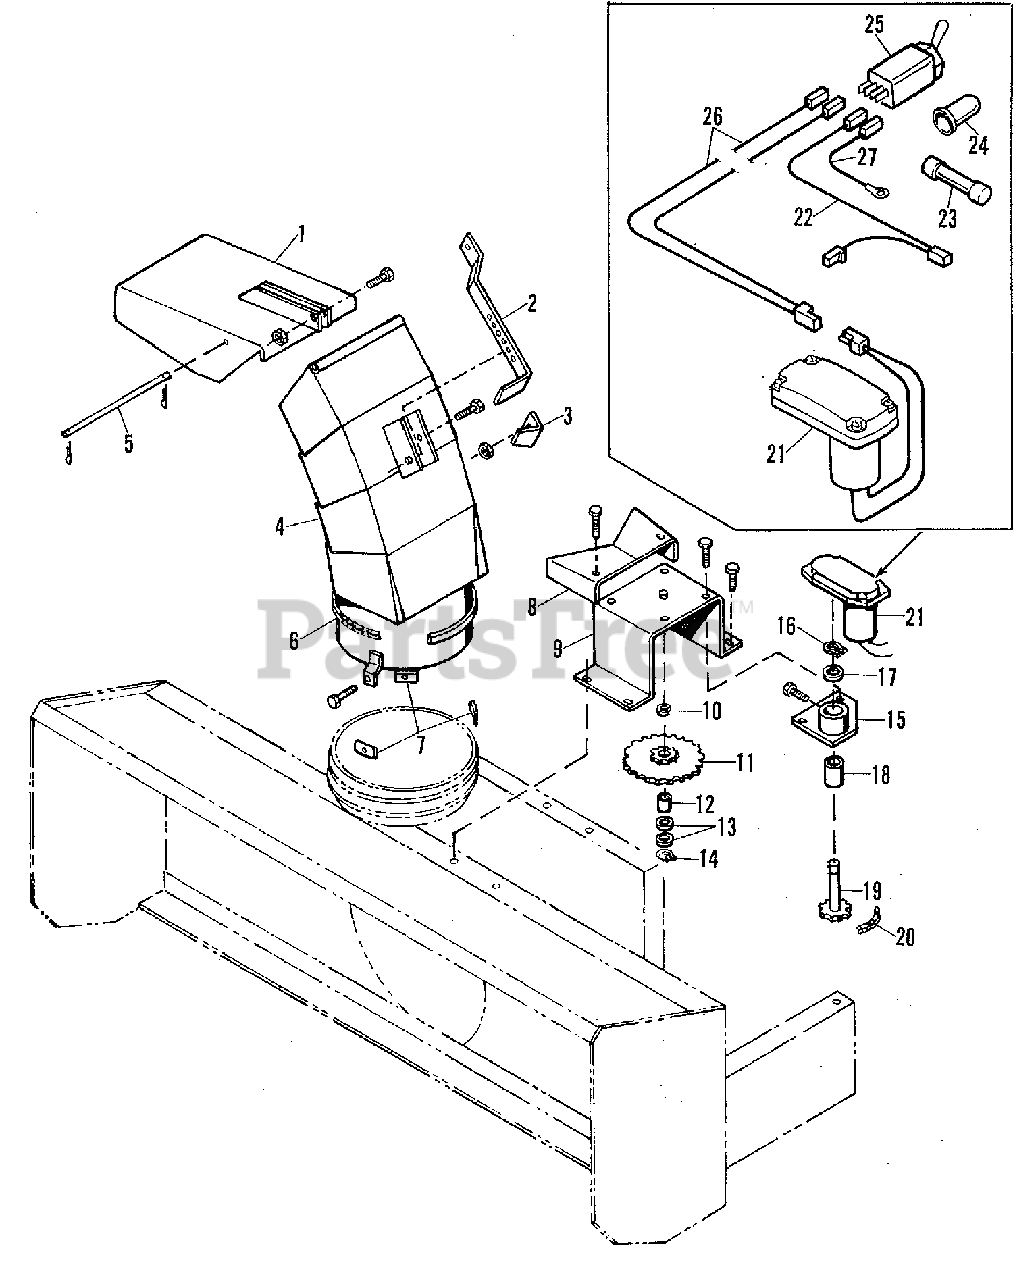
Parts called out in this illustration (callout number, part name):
1	CAPSCREW, 1/2NC x 1-1/4
1	NUT, Huglock, 1/2NC
3	LOCK, Adjuster
3	CAPSCREW, 1/2NC x 1
3	NUT, Huglock, 1/2NC
4	SPOUT ASSEMBLY
4	CAPSCREW, 3/8NC x 3/4
4	WASHER, Plain, 7/16 x 1 x 14 Ga.
5	PIN, Cotter, 1/8 x 1
6	CHAIN, 1/2 Pitch (Chute Rotator)
6	CHAIN, Bulk, 1/2 Pitch (10ft. Roll)
6	CHAIN, Bulk, 1/2 Pitch (50Ft. Roll)
6	LINK, Roller
6	LINK, Offset
6	LINK, Connecting
8	SHIELD, Chain
8	CAPSCREW, 5/16 NC x 1/2
8	WASHER, Plain, 3/8 x 7/8 x 16 Ga.
8	NUT, 5/16NC
9	BRACKET, Chute Rotator
9	CAPSCREW, 3/8NC x 1
9	WASHER, Plain, 7/16 x 1 x 14 Ga.
9	LOCKWASHER, 3/8
10	SPACER, Idler
13	BUSHING, Machine
14	RING, Retaining
15	BRACKET, Actuator
15	CAPSCREW, 3/8NC x 1
15	CAPSCREW, 3/8NC x 1-1/4
15	WASHER, Plain, 7/16 x 1 x 14 Ga.
16	RING, Retaining
18	BUSHING, Bronze
19	SHAFT, Drive
20	CHAIN, 3/8 Pitch (Chute Actuator)
20	CHAIN, Bulk, 3/8 Pitch (10ft. Roll)
20	CHAIN, Bulk, 3/8 Pitch (50ft. Roll)
20	LINK, Roller
20	LINK, Offset
20	LINK, Connecting
21	MOTOR & GEARBOX ASSEMBLY
22	HARNESS, Wiring
23	FUSE, 20 Amp (Tractor Fuse Box)
24	BOOT, Switch
25	SWITCH, Electric Toggle
26	WIRE ASSEMBLY (Electric Clutch & Spout Control
27	WIRE ASSEMBLY, Ground
